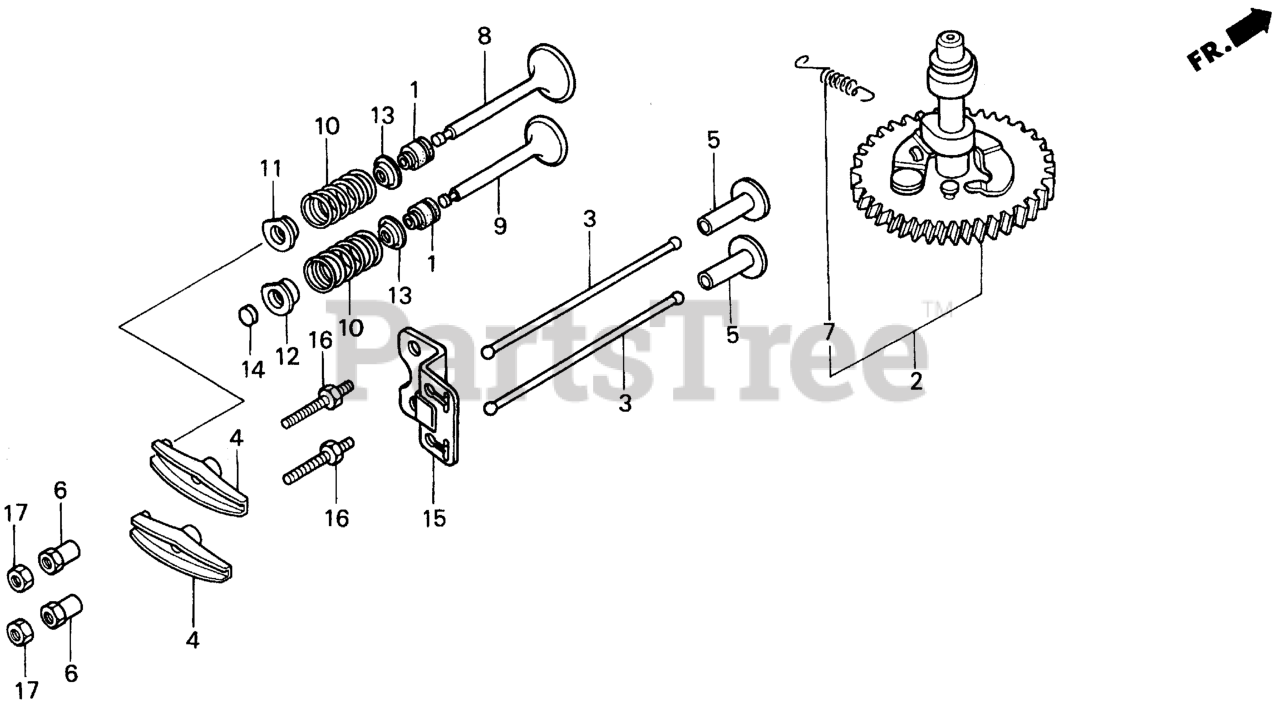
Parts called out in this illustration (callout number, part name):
1	SEAL, VALVE STEM
2	CAMSHAFT
2	CAMSHAFT ASSY.
3	ROD, PUSH
4	ARM, VALVE ROCKER
5	LIFTER, VALVE
6	PIVOT, ROCKER ARM
7	SPRING, WEIGHT RETURN
8	VALVE, IN.
9	VALVE, EX.
10	SPRING, VALVE
11	RETAINER, IN. VALVE SPRING (EXHAUST SIDE)
12	RETAINER, EX. VALVE SPRING
13	SEAT, VALVE SPRING
14	ROTATOR, VALVE
15	GUIDE, PUSH ROD
16	BOLT, PIVOT (8MM)
17	NUT, PIVOT ADJ.
